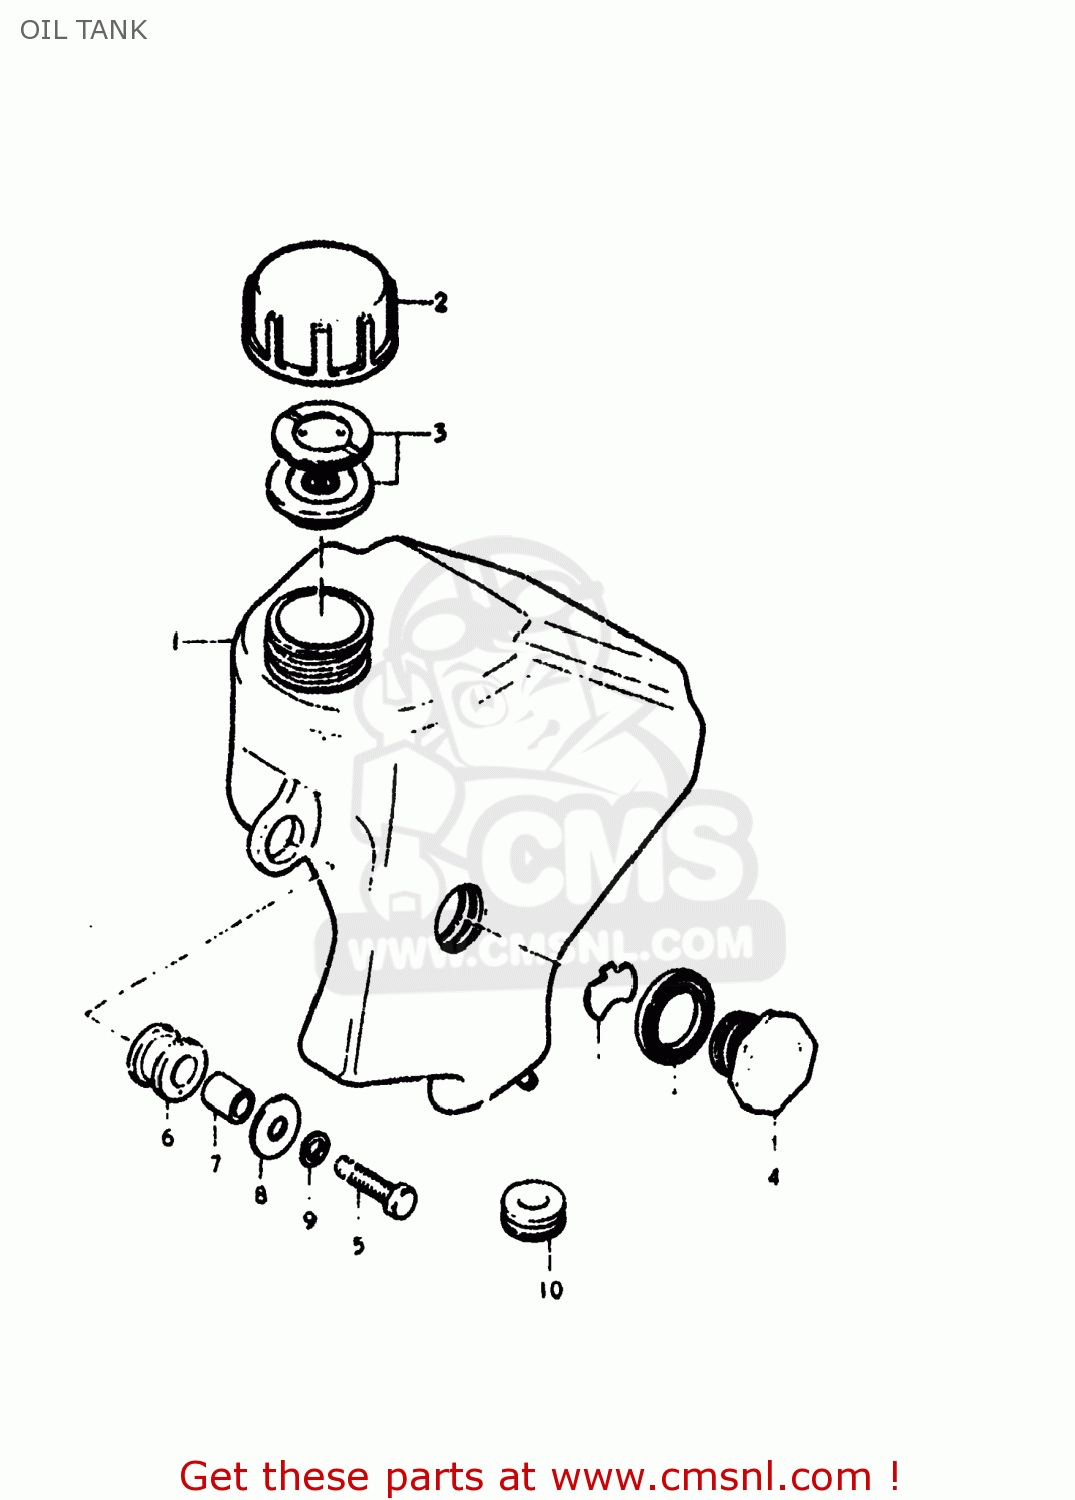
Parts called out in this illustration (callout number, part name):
1	TANK,OIL
2	CAP,OIL TANK
3	GASKET SET,OIL TANK CAP
4	LENS,OIL LEVEL INSPECTION
5	BOLT
6	CUSHION
7	SPACER (6.8X10X10)
8	WASHER
9	LOCK WASHER
10	CUSHION
